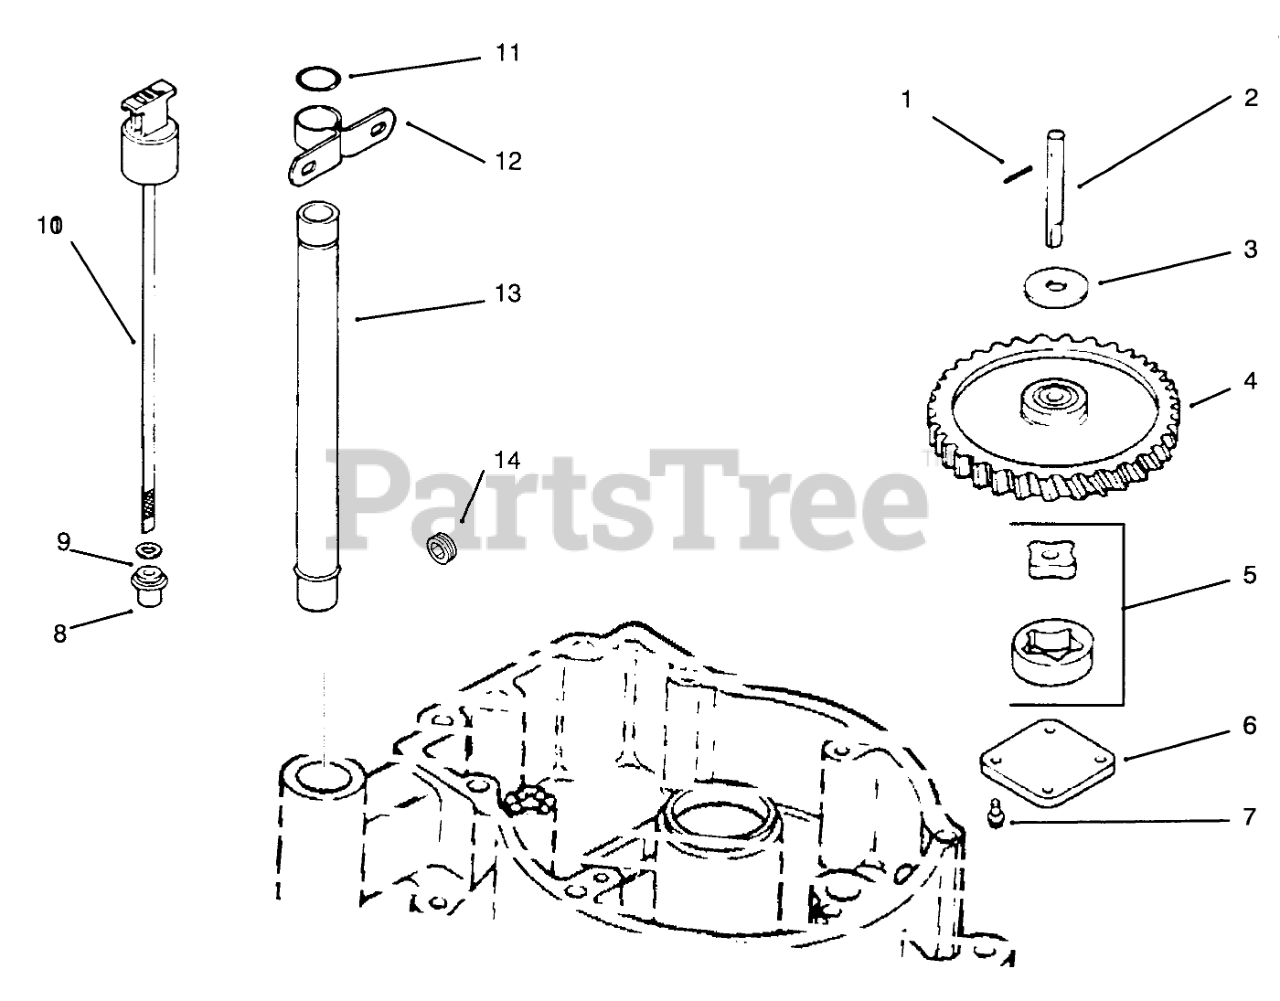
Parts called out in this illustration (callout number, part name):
1	Pin-Roll
2	Shaft-Oil Pump
3	Spacer-Shim
4	Gear-Oil Pump
5	Rotor Set
6	Cover-Oil Pump
7	Screw
8	Seal-Rubber
9	Screw
10	Dipstick (Incl. Ref. #8-9)
11	O-Ring
12	Bracket-Oil Tube Support
13	Tube-Oil Fill
14	Plug-Cup
